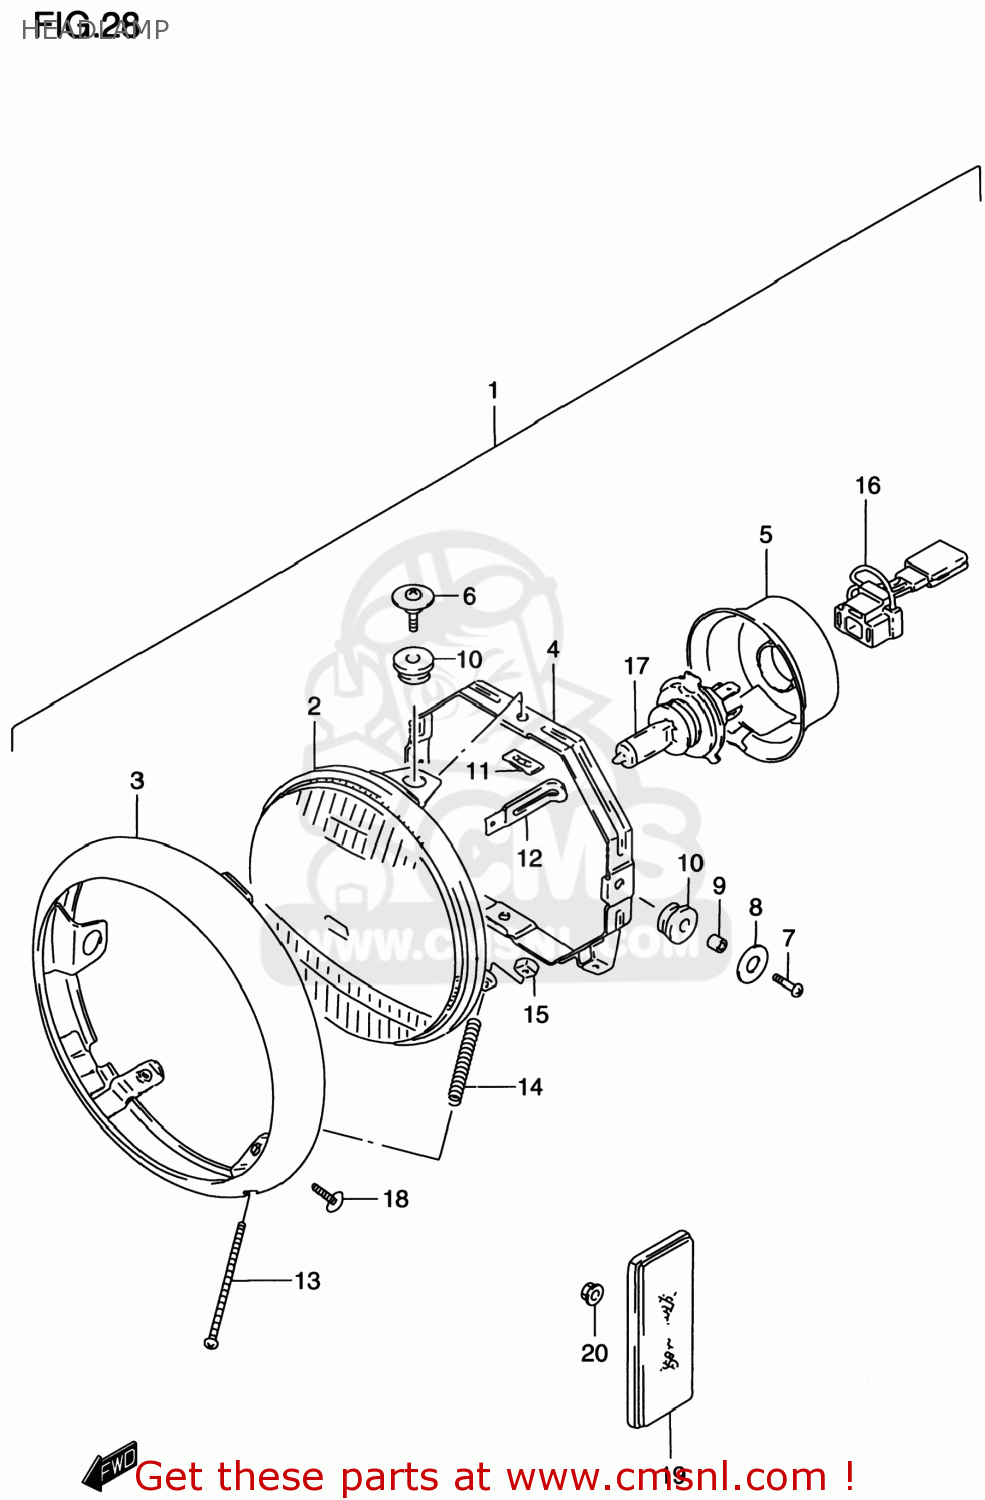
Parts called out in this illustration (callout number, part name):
1	HEADLAMP ASSY
2	UNIT,LAMP
3	RIM
4	RING,MOUNTING
5	COVER,SOCKET
6	SCREW,MOUNTING
7	SCREW(5X14)
8	WASHER (5.5X18X1)
9	SPACER
10	CUSHION
11	NUT
12	CLAMP(L:45)
13	SCREW,ADJUSTING(4X50)
14	SPRING
15	NUT
16	SOCKET
17	BULB(12V60/55W,H4)
18	SCREW
19	REFLEX REFLECTOR,FR SIDE
20	NUT
